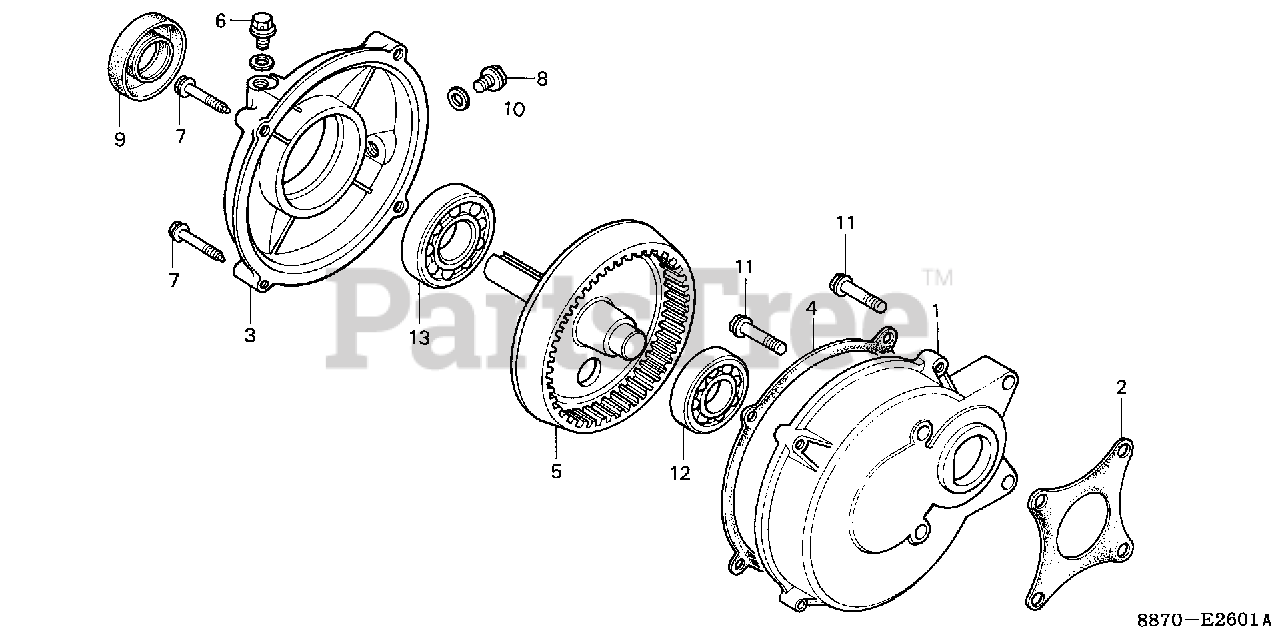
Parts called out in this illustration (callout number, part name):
1	CASE, REDUCTION
2	GASKET, REDUCTION CASE
3	COVER, REDUCTION
4	GASKET, REDUCTION COVER
5	SHAFT, P.T.O. (86T)
6	BOLT, BREATHING
7	BOLT, FLANGE (8X35)
8	BOLT, DRAIN PLUG (12X15)
9	OIL SEAL (25X41X6)
10	WASHER, DRAIN PLUG (12MM)
11	BOLT, FLANGE (8X32)
12	BEARING, RADIAL BALL (6204)
13	BEARING, RADIAL BALL (6305)
